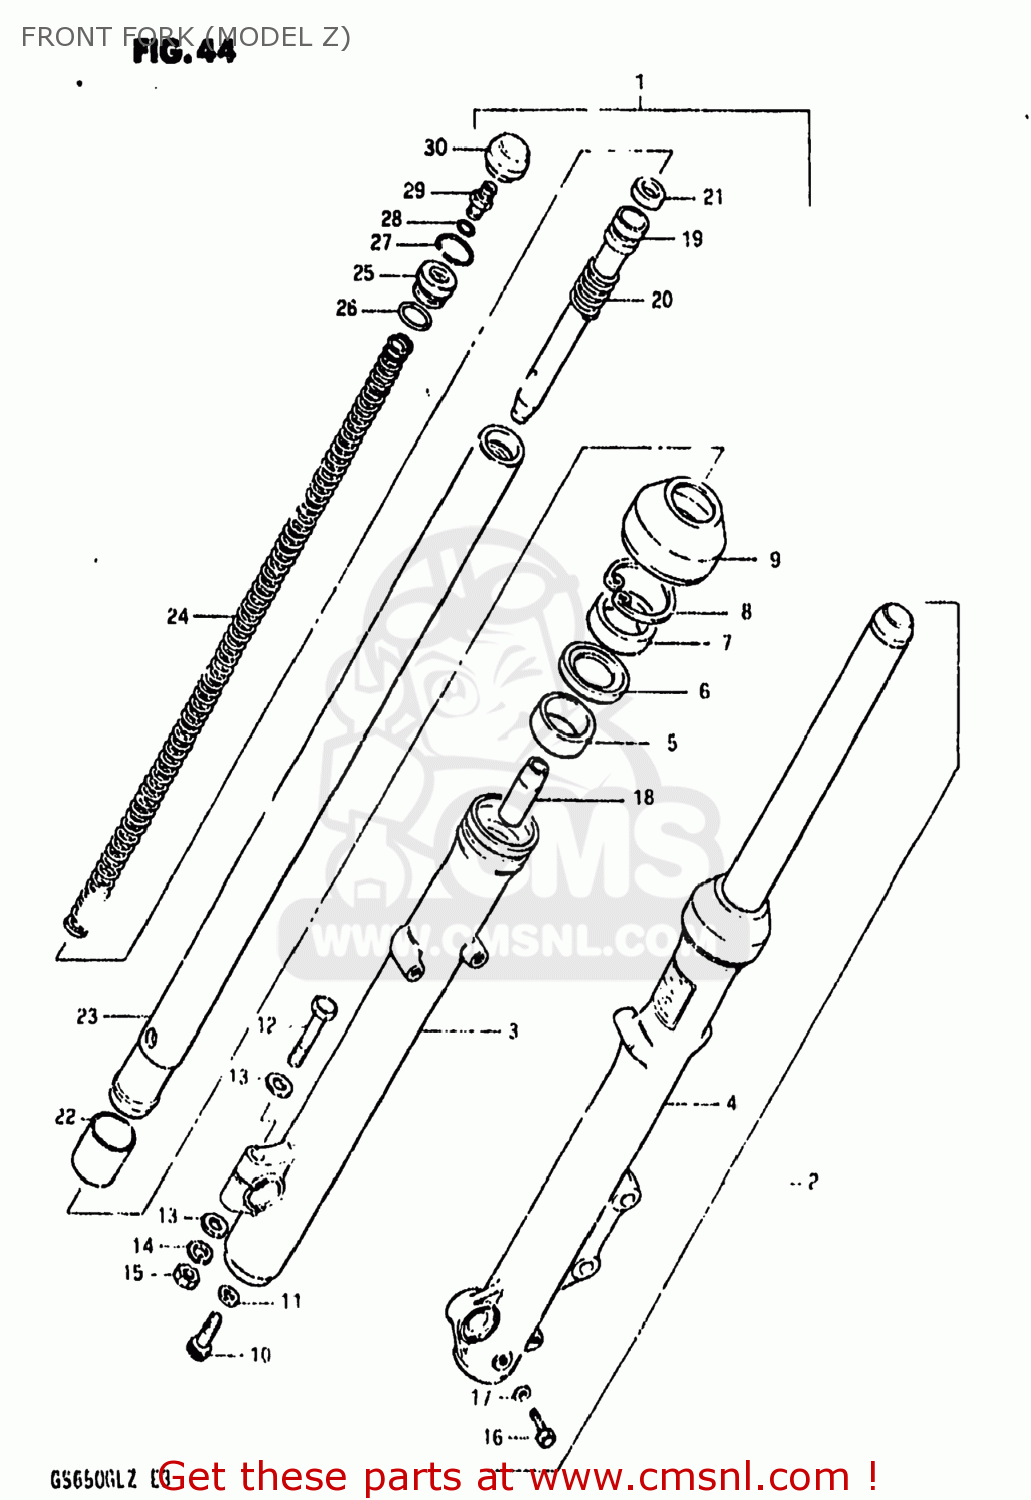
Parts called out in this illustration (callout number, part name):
1	DAMPER ASSEMBLY,RIGHT
2	DAMPER ASSEMBLY,FRONT FORK,LEFT
3	TUBE,FORK,OUTER,RIGHT
4	TUBE,OUTER,LEFT
5	BUSH,GUIDE
6	SPACER,SEAL
7	OIL SEAL,FRONT FORK
8	CIRCLIP,FORK OIL SEAL
9	BOOT
10	BOLT(8X27)
11	GASKET (NAS)
12	BOLT 8X50
13	WASHER
14	LOCK WASHER
15	NUT
16	BOLT
17	GASKET,DRAIN,PLUG (NAS)
18	PIECE,OIL LOCK
19	SPRING,FORK REBOUND
20	CYLINDER,FRONT FORK
21	RING
22	PISTON
23	TUBE,FORK,INNER
24	SPRING,FRONT
25	SEAT,SPRING
26	O-RING
27	RING,STOPPER
28	O-RING
29	VALVE,AIR
30	CAP
